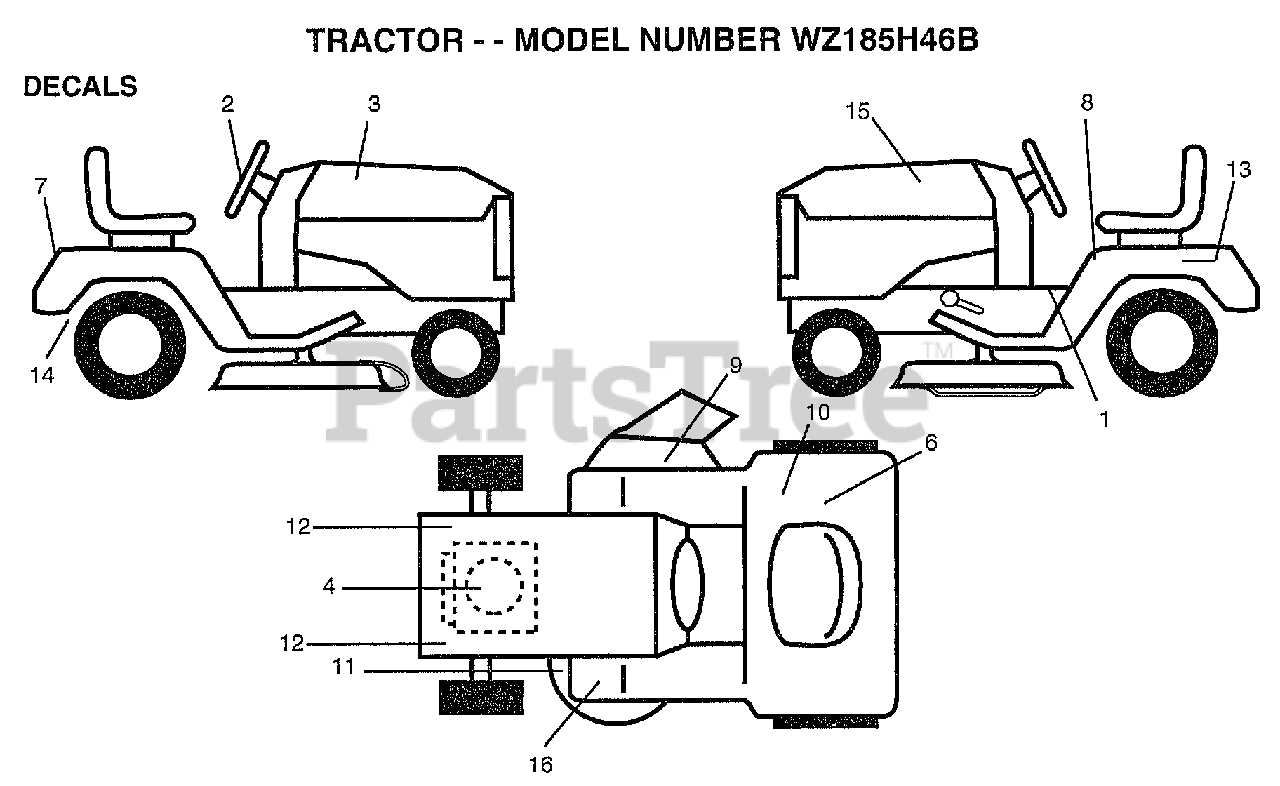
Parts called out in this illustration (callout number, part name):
1	DECAL BRAK PARK
2	DECAL.STRNG.WHL.WIZ
3	DECAL.HOOD.RH
4	DECAL.HP.ENGINE
7	DECAL.FENDER
8	DECAL.READ.O.MANU
9	DECAL.DANGER.CUTF
10	DECAL.EURO.ST.CE.
11	"DECAL.V.BELT.44"""
12	"DECAL CHASSIS,HOT"
13	DECAL.BATRY.3-3908
14	DECAL DRAWBAR LH
16	DECAL-BRAKE/CLUTC
